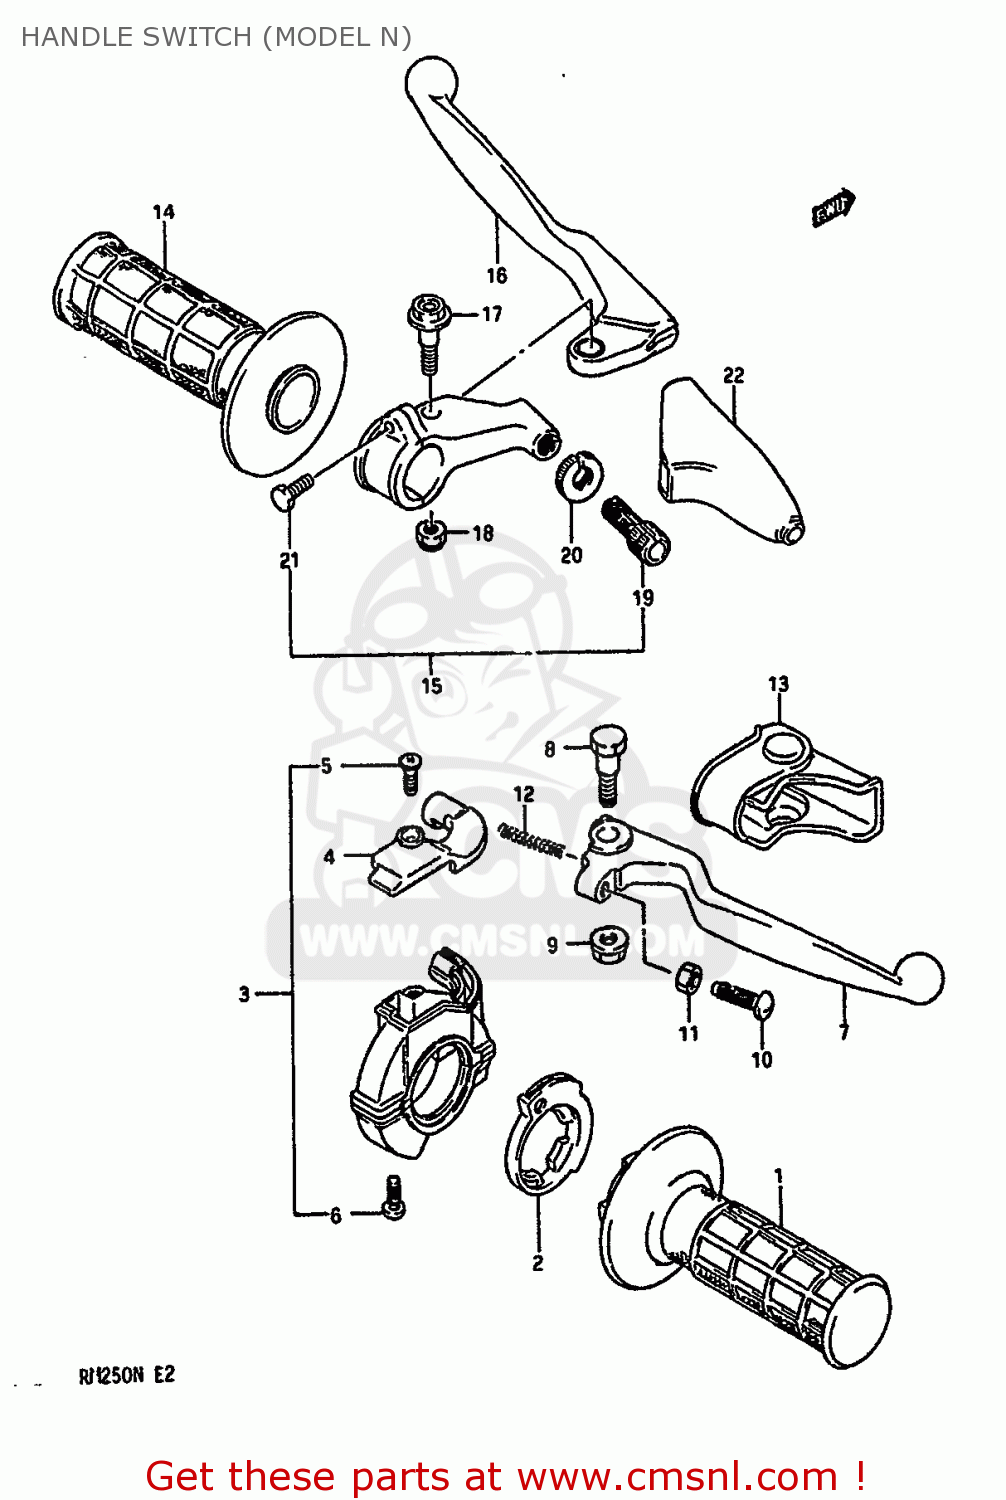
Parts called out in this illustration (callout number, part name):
1	GRIP,THROTTLE
2	ROTOR,THROTTLE GRIP
3	CASE ASSY,THROTTLE
4	COVER,THROTTLE CASE
5	SCREW 4X10
6	SCREW
7	LEVER,BRAKE
8	BOLT,BRAKE LEVER
9	NUT,BRAKE LEVER
10	BOLT,ADJUST
11	NUT ,5MM
12	SPRING,RETURN
13	COVER,BRAKE LEVER
14	GRIP,L
15	LEVER ASSEMBLY,CLUTCH
16	LEVER,CLUTCH
17	BOLT,LEVER
18	NUT 6MM
19	ADJUSTER,WIRE
20	NUT,LOCK
21	BOLT
22	COVER,CLUTCH LEVER
23	SCREW(5X14)
24	COVER,CLUTCH LEVER
